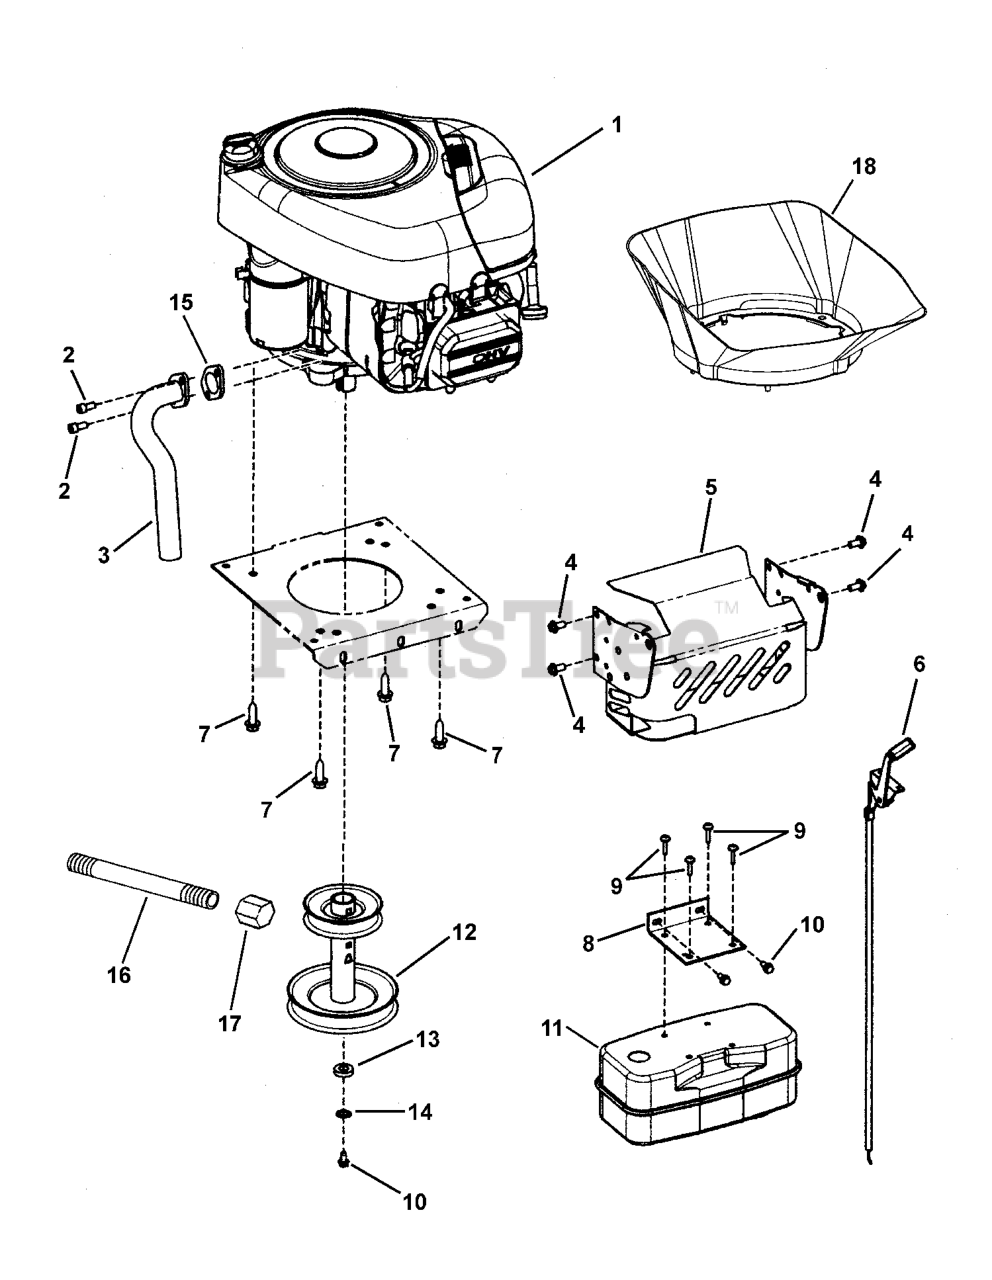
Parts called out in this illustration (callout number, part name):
1	* ENGINE, 18.5 B&S OHV IC (shown)
2	SCREW - TORX HEAD
3	EXHAUST TUBE SINGLE
3	TUBE, EXHAUST, MOD 21
4	5/16-18 HER HEX HEAD
5	ASSY - HEAT SHIELD
6	THROTTLE CONTROL
7	HHST, 3/8-16X1.25
8	BRKT - MUFFLER
9	SCREW - THREAD FORMING, 0.88 X 3/16-15
10	SCREW .25-20 X0.59 HEX
11	MUFFLER - SINGLE
12	ASSY, STACK PULLEY
13	HER .470- 1.00.25 FLT
14	HER .43-.074 X .04 STAR
15	GASKET-EXHAUST B&S REG (NO CHRE) 273485
16	PIPE NIPPLE .38X4.0
17	PIPE CAP,.38 ZINC
18	PLENUM, MURRAY
